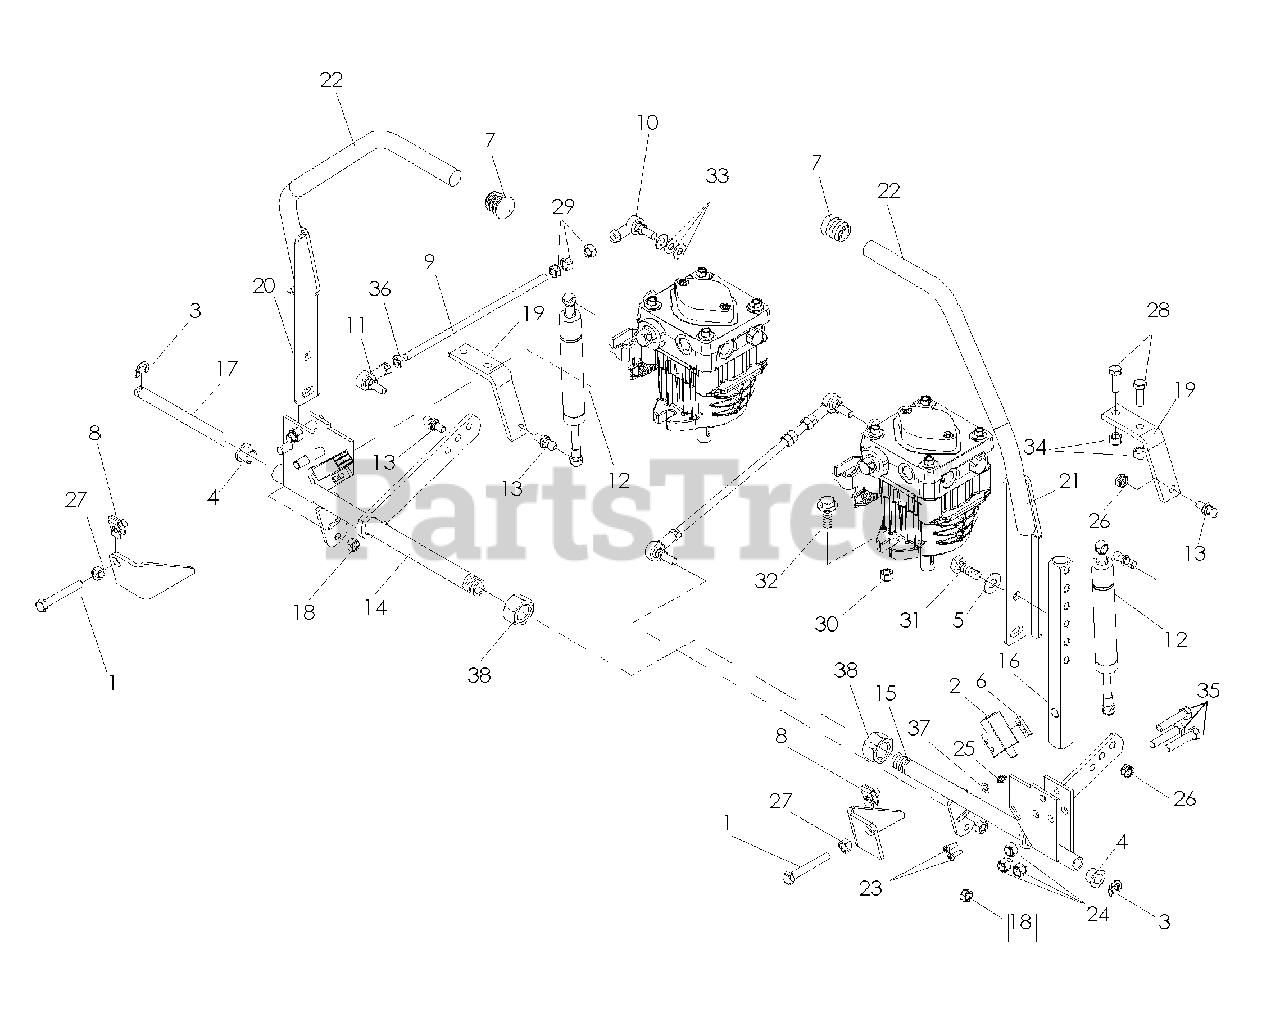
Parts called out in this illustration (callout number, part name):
1	BOLT HEX 1/4 X 1-1/4
2	SWITCH, INTERLOCK
3	E-RING 1/2 (2 2)
4	BUSHING
5	WASHER, 3/8 DISC SPRING SPEC
6	TAPPED PLATE
7	END PLUG 15/16` (BLACK)
8	U-CLIP 5/16-18 NUT RETAINER
9	PUMP CONTROL LINK
10	SPHERICAL ROD END, RH
11	SPHERICAL ROD END, LH
12	DAMPENER
13	STUD.BALL.10MM
14	CONTROL ASM - ADJ, RT
17	CONTROL SHAFT
18	NUT 5/16F NYLOC
19	DAMPENER BRACKET
20	LEVER, DRIVE, RT
21	LEVER, DRIVE, LT
22	GRIP, FOAM (GROUND) 15
23	SCREW #10-24 X 5/8
24	NUT 3/8-16 NYLOC
25	ZERK
26	NUT 5/16C CENTERLOCK
27	NUT 5/16C HEX
28	HCS 5/16C X 1
29	NUT 5/16F
30	NUT 3/8C CENTERBLOCK
31	HCS 3/8C X 1
32	HCS 3/8C X 1 SERRATED HEAD
33	WASHER 5/16 FLAT
34	NUT 5/16 NYLOC
35	HCS 3/8-16 X 1 3/4 GR5
36	NUT 5/16F LEFTHAND
38	NUT 3/4 X 16 HEX CTR
